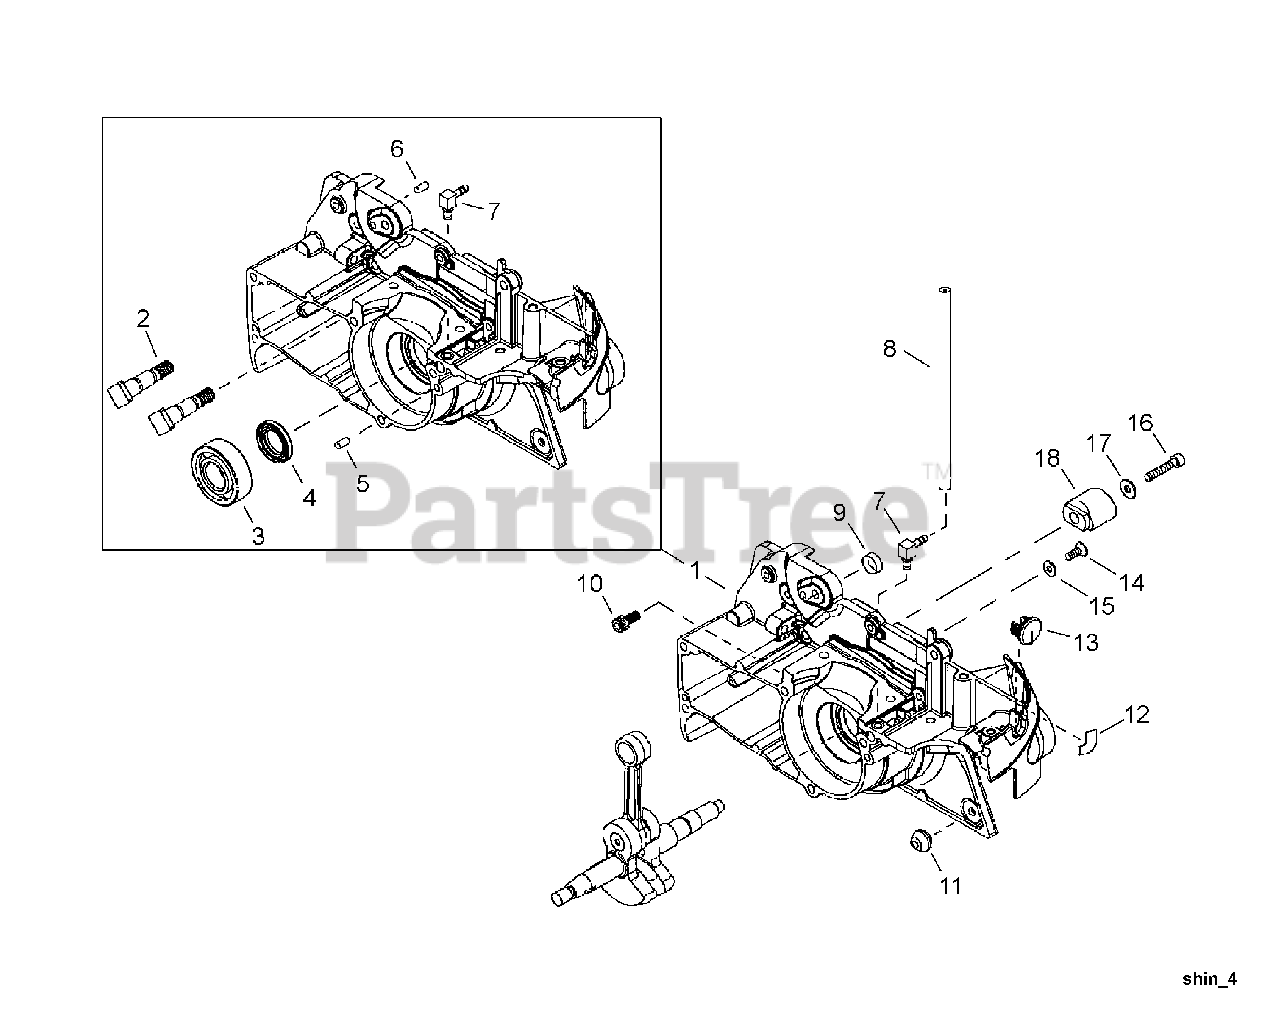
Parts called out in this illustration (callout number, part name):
1	CRANKCASE ASSY - RIGHT
2	STUD, GUIDE BAR
3	BEARING, BALL - 6202C3
4	SEAL, OIL
5	PIN - LOCATING
6	PIN - LOCATING
7	PULSE JOINT
8	PULSE TUBE
9	RING
10	SCREW - 5X12
11	SUPPORT C
13	PLUG
14	SCREW - 4X8
15	WASHER - 4
16	BOLT - 5X25
17	WASHER - 5
18	CATCHER, CHAIN
